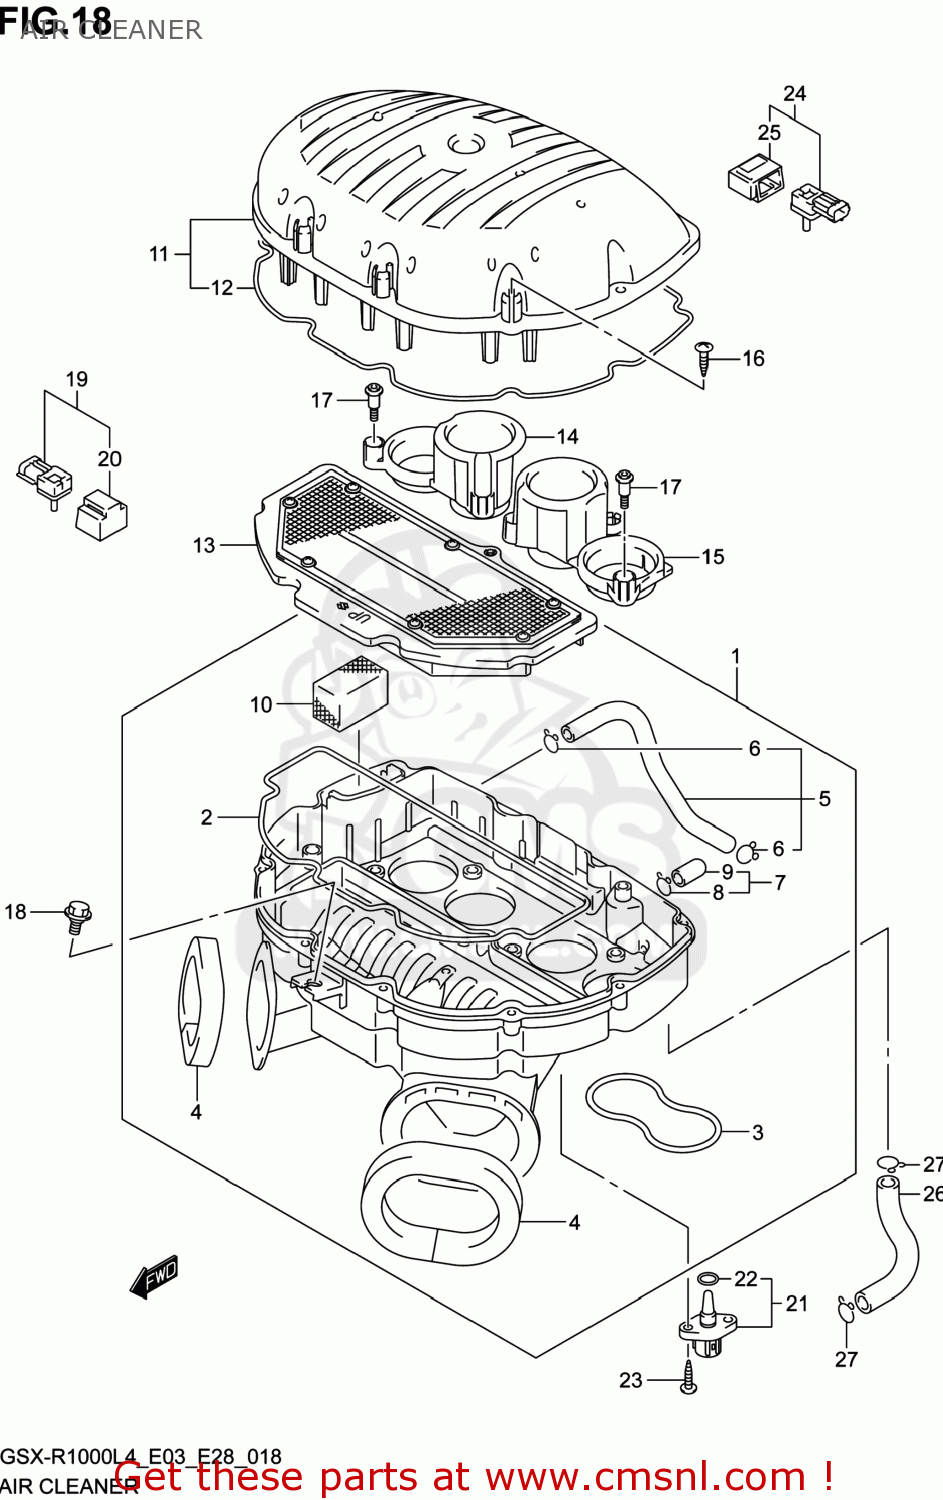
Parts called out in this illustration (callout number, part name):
1	CASE,AIR CLEANER
2	GASKET,CASE (NAS)
3	GASKET,CASE (NAS)
4	CUSHION,DUCT
5	TUBE,BREATHER
6	CLIP
7	PLUG ASSY,DRAIN
8	CLIP
9	PLUG
10	FILTER,BREATHER
11	CAP,AIR CLEANER
12	GASKET,CAP (NAS)
13	FILTER ASSY
14	FUNNEL,OUTLET,R
15	FUNNEL,OUTLET,L
16	SCREW
17	BOLT,AIR CLEANER CASE
18	BOLT(6X16)
19	SENSOR,BOOST
20	COVER
21	SENSOR,AIR TEMP
22	O RING
23	SCREW
24	SENSOR,AIR PRESSURE
25	COVER
26	HOSE,ISC VALVE
27	CLIP
